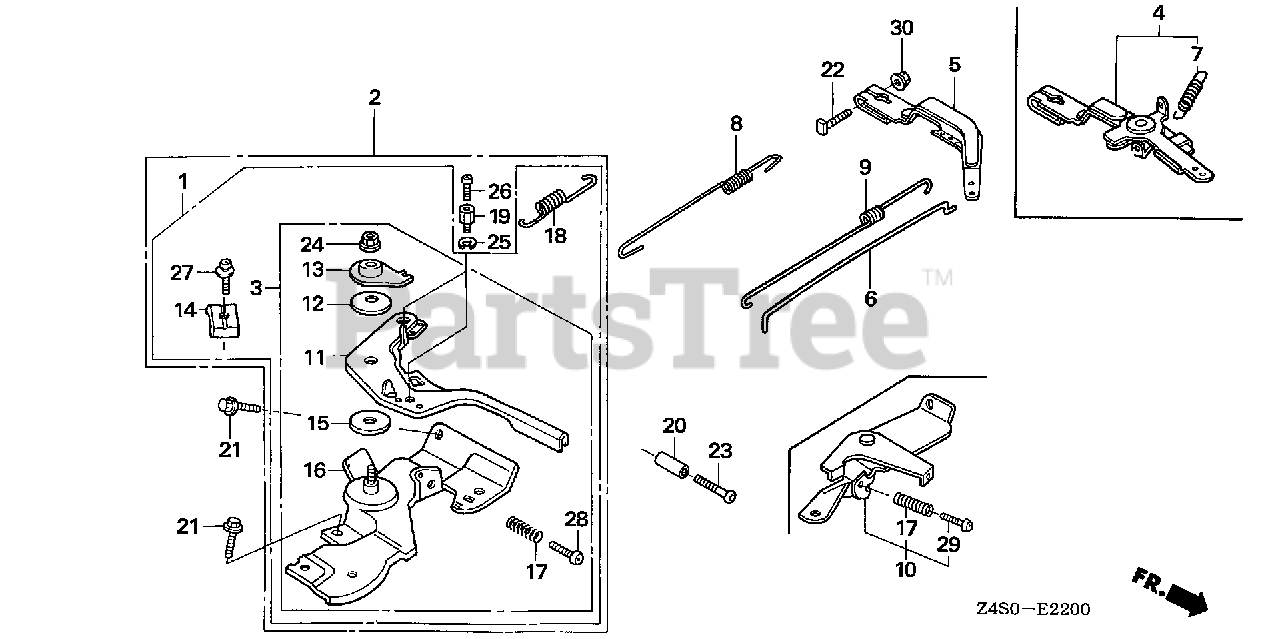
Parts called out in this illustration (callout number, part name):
5	ARM, GOVERNOR
6	ROD, GOVERNOR
8	SPRING, GOVERNOR
9	SPRING, THROTTLE RETURN
10	CONTROL ASSY.
17	SPRING, CONTROL ADJUSTING
20	COLLAR, STOPPER
21	BOLT, FLANGE (6X12) (CT200)
22	BOLT, GOVERNOR ARM
23	SCREW, RECESSED (5X25)
29	SCREW, PAN (5X35)
30	NUT, FLANGE (6MM)
